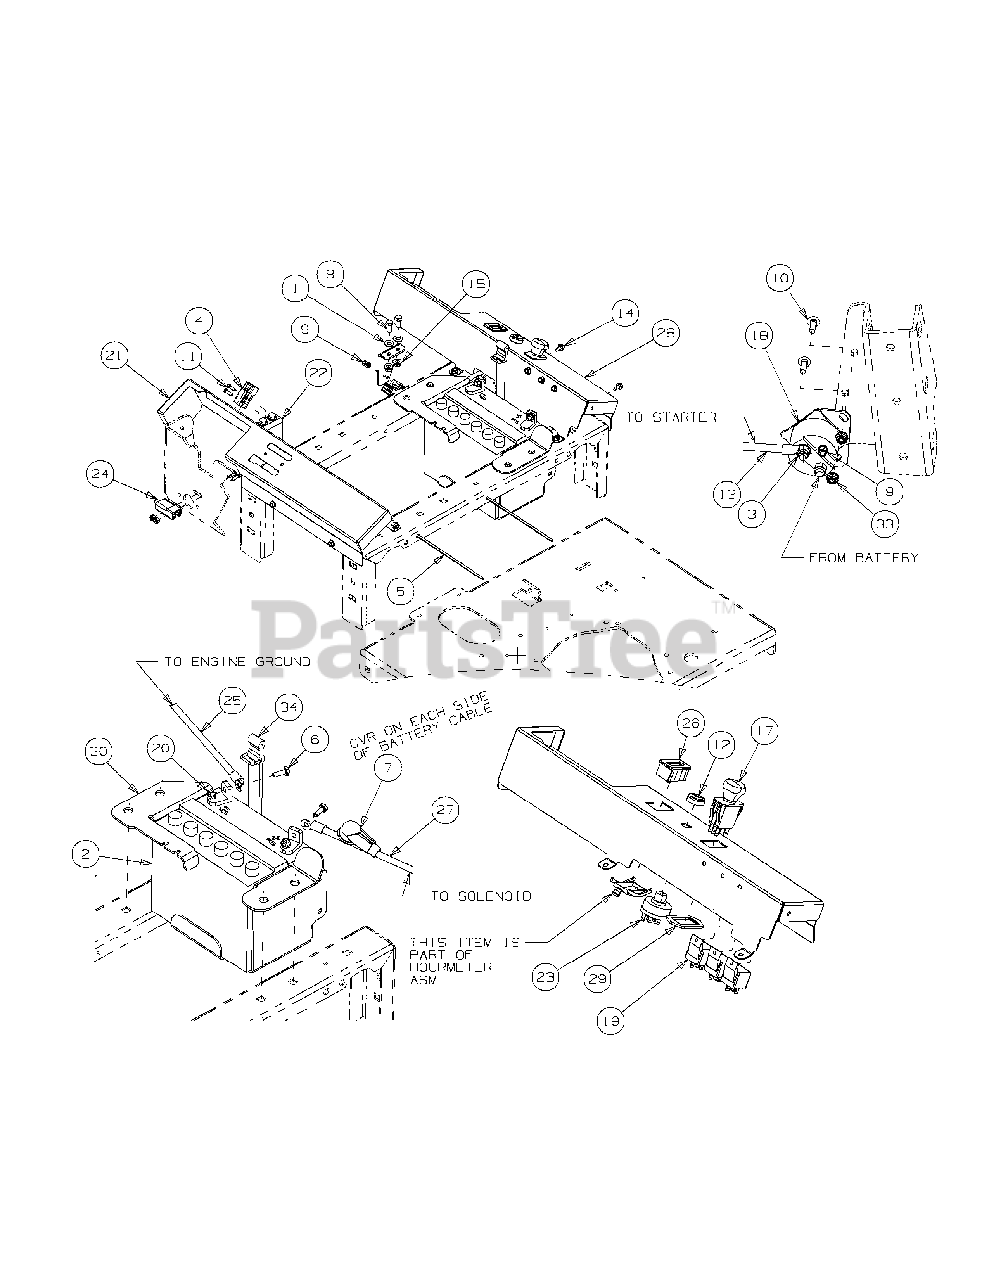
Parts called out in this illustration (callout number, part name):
1	Flat Washer, 5/16
2	Battery, 12V 225CCA 30 Min
3	Nylock Nut, 5/16-18
4	Switch, Safety
5	Tie, Cable, 3/16 x .05 x 7.4"
6	Screw, Hex, Cap, 1/4-20 x .75
7	Boot, 1" OD Rubber Battery-PST, Red
8	Hex Cap Screw, 5/16-18 x 3/4
9	Nut, Lock, Nylon Insert, #10-32
10	Carriage Bolt, 1/4-20 x .750
11	Screw, Phillips Head, Machine, 10-32 x 5/8
12	Nut, W/Cap, 5/8-32 Ignition
13	Cable, Battery, Red, 15"
14	Self Tapping Screw, 1/4-20 x 1/2
15	Hexflange Lock Nut, 5/16-18
17	Switch, Electric, PTO
18	Solenoid Magnetic Switch
19	Relay, 12V 40A
20	Hex Flange Lock Nut, 1/4-20
21	Control Panel, LH
22	Switch Mounting Bracket, Lapbar
23	Switch, Ignition, 6 Pin
23	Key, Ignition
24	Switch, Plunger
25	Cable, Battery Black, 28"
26	Meter, Hour includes:
27	Cable, Battery Red, 32"
28	Control Panel, RH
29	Bracket, PTO Switch Retainer
34	Strap, Battery
